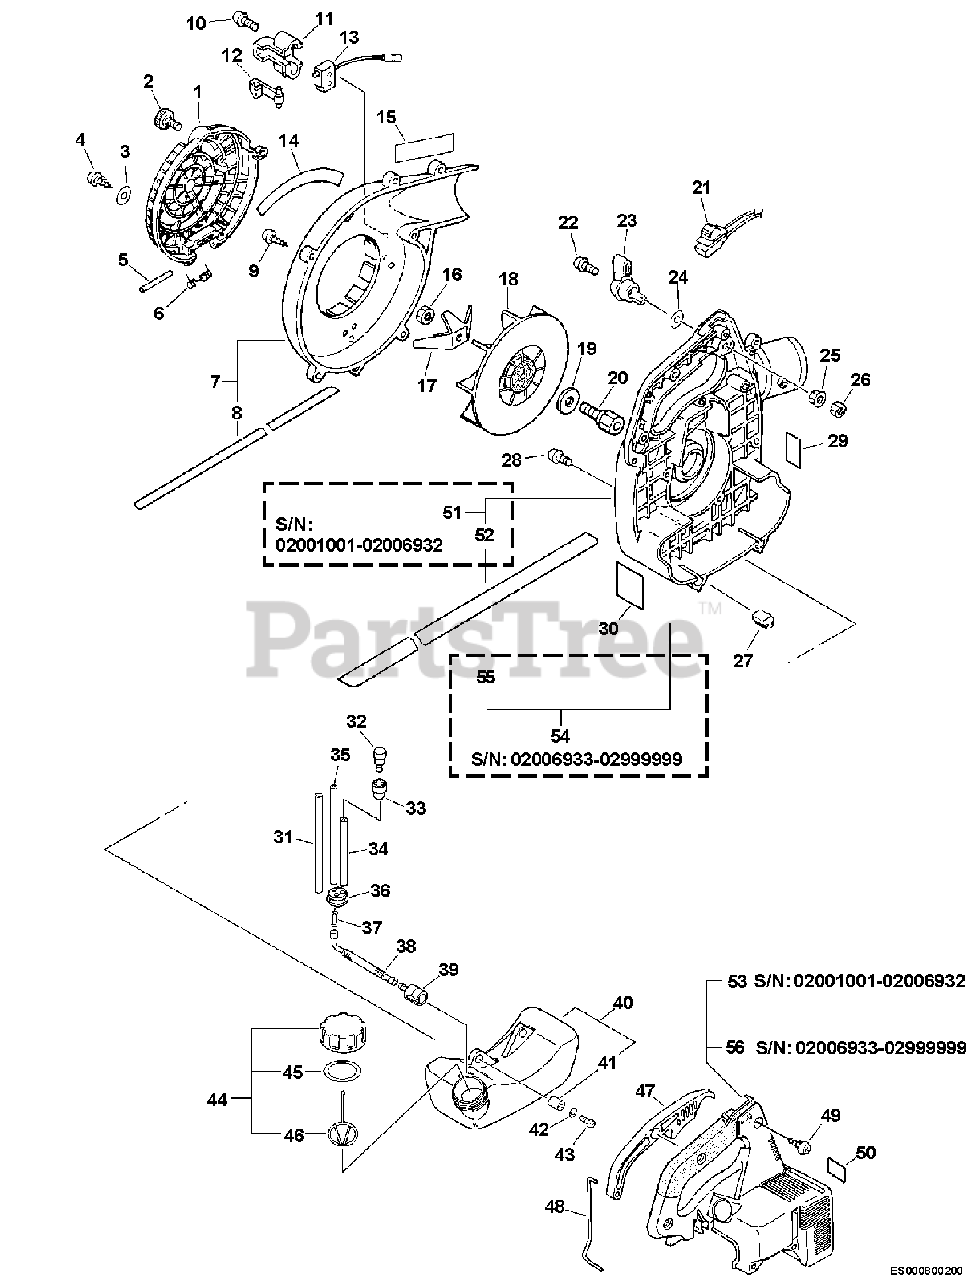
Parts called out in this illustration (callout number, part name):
1	GUARD, DEBRIS
2	THUMBSCREW
3	WASHER - 5
4	SCREW - 5X14
7	FAN CASE ASSY - LEFT
9	SCREW - 5X20 -- TAPPING
10	SCREW - 4X22
11	BRACKET, SWITCH - GRAY
12	ACTUATOR
13	IGNITION SWITCH ASSY
14	LABEL - MODEL ES-211
15	LABEL - CAUTION
17	BLADE, SHREDDER
19	WASHER - 8
20	HUB, FAN
21	IGNITION SWITCH ASSY
22	SCREW - 5X25
23	LEVER, THROTTLE - ORANGE
24	WASHER - 5
25	NUT - 5 -- FLANGE
28	SCREW - 4X22
29	LABEL - CAUTION -- SPANISH
30	LABEL - CAUTION
31	PIPE - 3X6X90 -- CLEAR
32	VENT, FUEL TANK
33	COVER, VENT
34	PIPE - 3X5X70 -- BLACK
35	PIPE - 3X5X90 -- BLACK
36	GROMMET
37	CONNECTOR, PIPE
38	PIPE, FUEL - CORRUGATED
39	FILTER, FUEL
40	FUEL TANK ASSY
42	WASHER - 5
43	SCREW - 5X16
44	CAP ASSY - ORANGE
45	GASKET, CAP
46	CONNECTOR, CAP
47	TRIGGER, THROTTLE - ORANGE
48	ROD, THROTTLE
49	SCREW - 5X20 -- TAPPING
50	LABEL - HOT SURFACE
51	FAN COVER ASSY - RIGHT
53	COVER, ENGINE - GRAY
54	FAN COVER ASSY - RIGHT
56	COVER, ENGINE - GRAY
